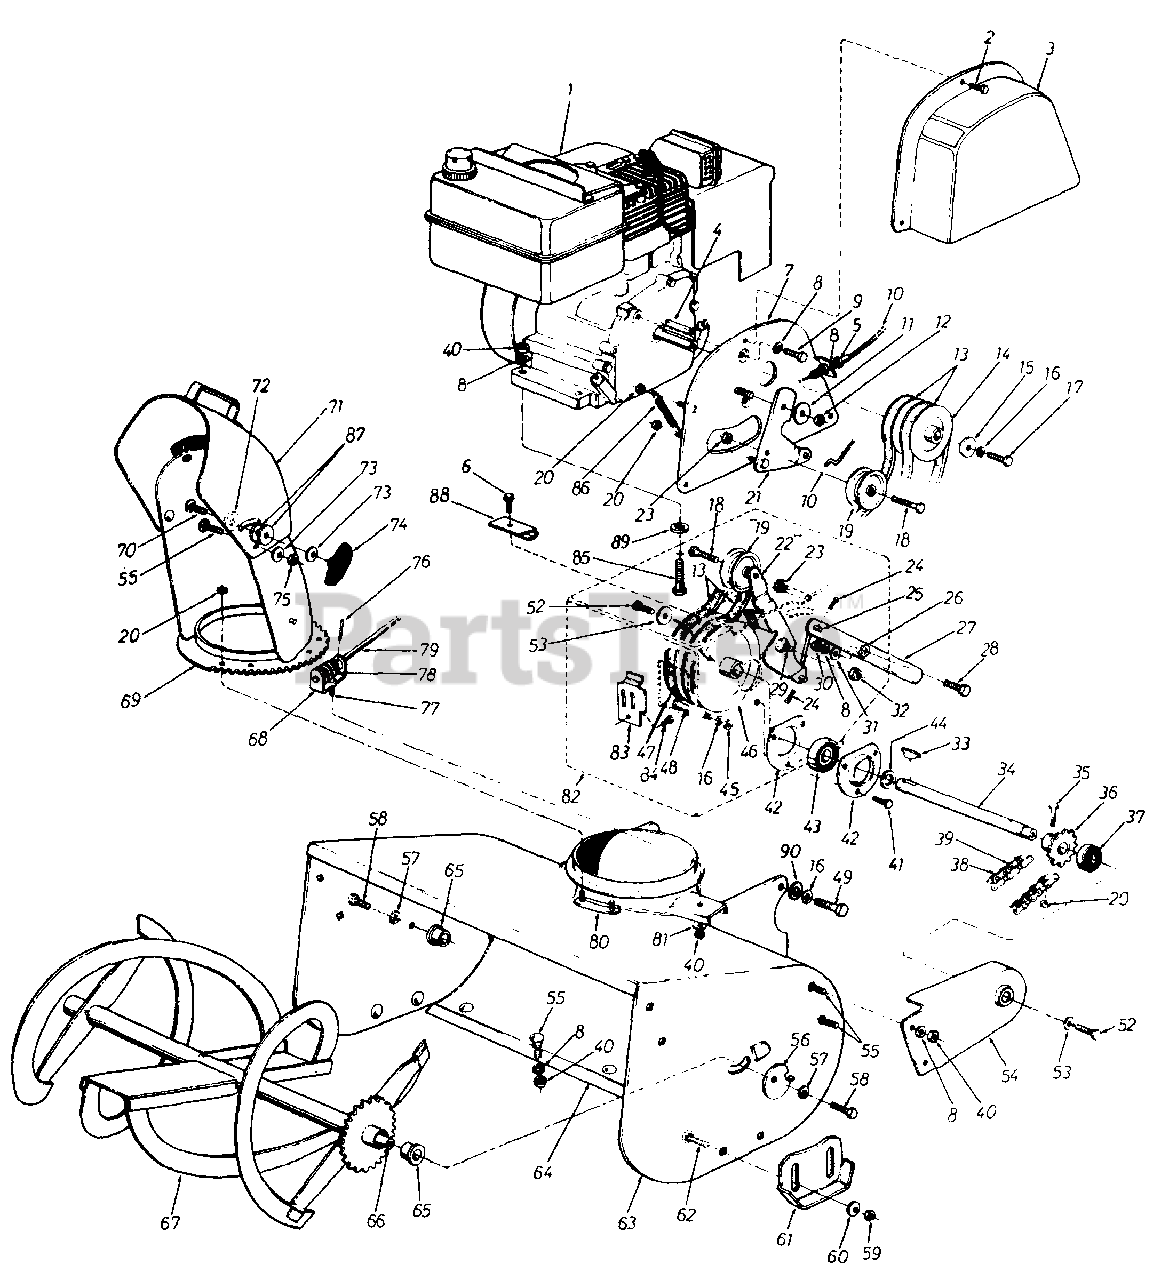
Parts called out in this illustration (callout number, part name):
1	Engine
2	Hex Self-Tap Scr. 1/4-20 x .50" Lg.
3	Belt Cover
4	Sq. Key 3/16 x 1.00" Lg.
5	Hex Jam Nut 5/16-24 Thd.
6	Hex Wash. Hd. Self-Tap Scr. 5/16-24 x .50" Lg.
7	Engine Plate Ass'y.
8	L-Wash. 5/16" Scr.
9	Hex Scr. 5/16-24 x .62" Lg.
10	Drive Clutch Control Cable
11	Fl-Wash. .39 I.D. x 1.50 O.D. x .060
12	Hex Ins. Jam L-Nut 3/8-24 Thd.
13	3 V-Belt 31.5" Lg.
14	Engine Pulley
15	Fl-Wash. .40 I.D. x 1.25 O.D. x .157
16	L-Wash. 3/8" Scr.
17	Hex Scr. 3/8-24 x 1.00" Lg.
18	Hex Scr. 3/8-16 x 1.25" Lg.
19	Flat Idler 2.25 O.D.
20	Hex Cent. L-Nut 1/4-20 Thd.
21	Drive Idler Bracket Ass'y.
22	Thrower Idler Bracket Ass'y.
23	Hex Cent. Jam L-Nut 3/8-16 Thd.
24	Cotter Pin 3/32" Dia. x 1.00" Lg.
25	Clutch Rod 5/16" Dia. x 2.88 Lg.
26	Shoulder Spacer
27	Thrower Clutch Bracket
28	Hex Sems Scr. 5/16-18 x 1.00" Lg.
29	Shoulder Scr. .625" Dia. x .170"
30	Hex Cent. L-Nut 5/16-18 Thd.
31	Fl-Wash. .34 I.D. x 1.12 O.D. x .125
32	Hex Cent. Jam L-Nut 3/8-16 Thd.
33	Woodruff Key 5/32 x 5/8 Dia.
34	Thrower Shaft 20" and Snap Ring
35	Hex Scr. 1/4-20 x 1.50" Lg.
36	14 Teeth Sprocket Hub Ass'y.
37	Ball Bearing .625 I.D. x 1.38 O.D. x .438
38	#41 Chain - 1/2" Pitch x 63 Links
39	#41-Master Link 1/2" Pitch Type II
40	Hex Nut 5/16-18 Thd.
41	Hex Wash. Hd. Self-Tap Scr. 5/16-24 x .50" Lg.
42	Bearing Housing
43	Self Aligning Bearing .750 I.D.
45	Hex Nut 3/8-16 Thd.
46	1/2" V-Pulley .753 I.D.
47	5.25" O.D. Pulley with 9 Teeth Sprocket
48	Shoulder Scr. .498" Dia. x 2.475" Lg.
49	Hex Self-Tap Scr. 3/8-16 x 75"
52	Hex L-Scr. 5/16-18 x .62" Lg.
53	Belleville Wash. .34 I.D. x .88 O.D. x .060
54	Chain Guard
55	Carriage Bolt 5/16-18 x .62" Lg.
56	Chain Adjuster
57	L-Wash. 3/8" Scr.
58	Hex Scr. 3/8-24 x 1.00" Lg.
59	Hex Nut 3/8-16 Thd.
60	Belleville Wash. .40 I.D. x .88 O.D.
61	Slide Shoe
62	Carriage Bolt 3/8-16 x .75" Lg.
63	Spiral Housing Ass'y. 20"
66	Spiral Shaft
67	Spiral Ass'y. - 20"
68	Chute Bracket
69	Chute Ass'y.
70	Carriage Bolt 5/16-18 x 1.00" Lg.
71	Top Chute Ass'y.
72	Fl-Wash. .53 I.D. x 1.25 O.D. x .100
73	Belleville Wash. .34 I.D. x .88 O.D.
74	Handle Knob Ass'y.
75	Hex Cent. L-Nut 5/16-18 Thd.
76	Spring Pin Roll 1/8" Dia. x .75" Lg.
77	Carriage Bolt 5/16-18 x .62" Lg.
78	Worm - R.H. with Three Thread
79	Chute Crank
80	Chute Flange Keeper Ass'y.
81	Belleville Wash. .34 I.D. x .88 O.D.
82	Frame Ass'y.
83	Belt Guard Plate
84	Hex Wash. Self-Tapp Scr. 5/16-18 x .75" Lg.
85	Hex Scr. 5/16-18 x 1.50" Lg.
86	Extension Spring .38 O.D. x 2.50" Lg.
88	Belt Guard
89	Fl-Wash. .34 I.D. x .62 O.D. x .060
90	Fl-Wash. 3/8" I.D.
